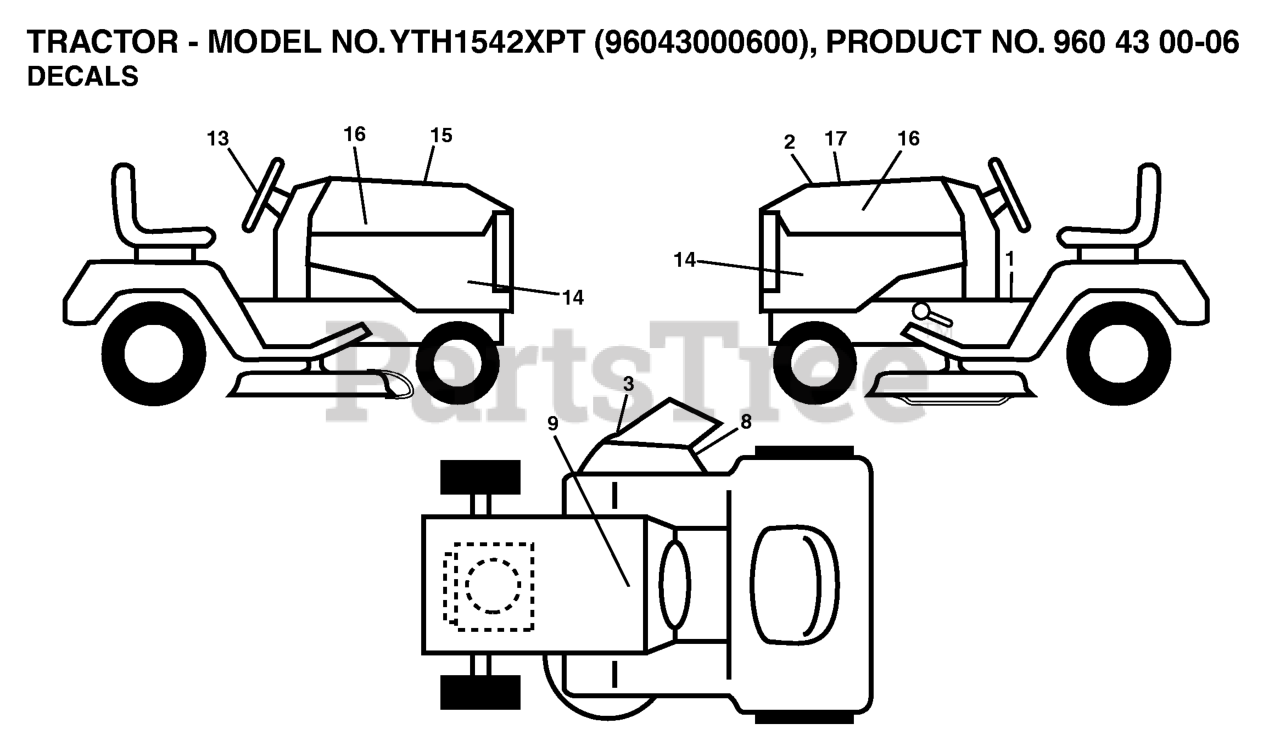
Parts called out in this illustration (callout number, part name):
1	DECAL.FENDER.OPER.TEX.
2	DECAL.HOOD.TOP.INSERT.
3	DECAL.WARN.KEEP.HAND.AWAY
8	DECAL V BELT SCHEMATIC
9	DECAL BTRY SYMBOLS
13	DECAL.STEERING.HUSQ.BLUE
14	DECAL.SDPANEL.YTH1542X
15	DECAL HOOD CUST. RESP.
16	DECAL.HOOD.NAMELOGO.HUSQ
17	DECAL.RPL.KAWA.15HP.42
